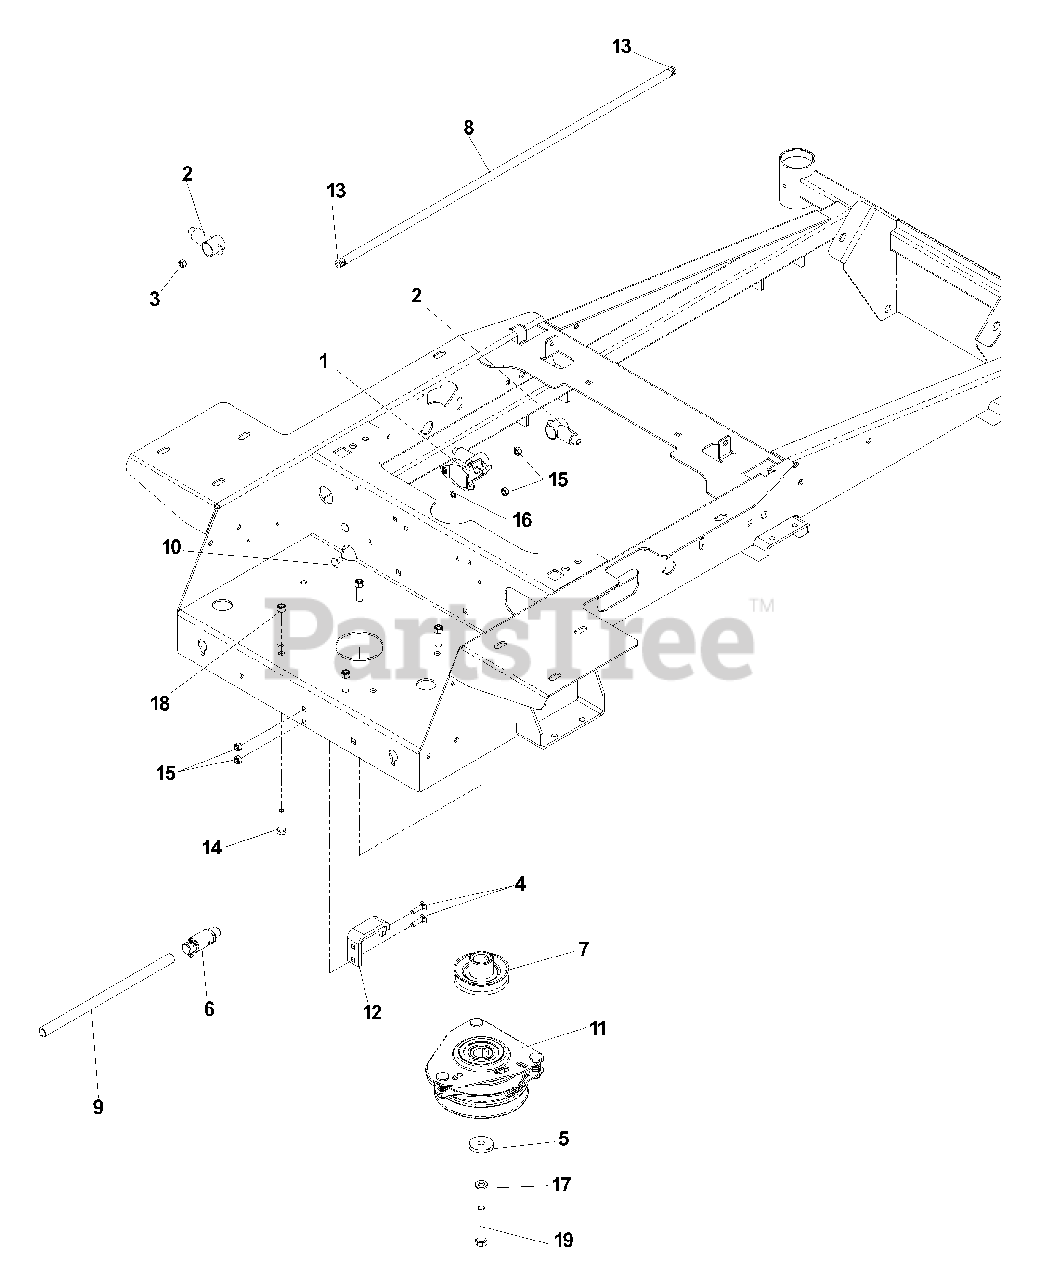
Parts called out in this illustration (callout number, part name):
2	INSULATOR, BATTERY
3	NUT, 1/4-20, THIN NYLOC
4	RHSNB, 1/4-20 X 1, GR5
5	CLUTCH WASHER
6	OIL DRAIN FITTING
8	FUEL LINE, 24"
9	FUEL LINE, 5"
10	RHSSNB, 1/4-20 X 5/8, GR5
12	CLUTCH TIE DOWN
13	CLAMP, HOSE
14	HCS, 5/16-18 X 1 1/2, GR5
15	NUT, 1/4-20, NYLOC
16	WASHER, 1/4
17	WASHER, 7/16
18	NUT, 5/16-18, NYLOC
19	HCS, 7/16-20 X 2 1/2, GR5
